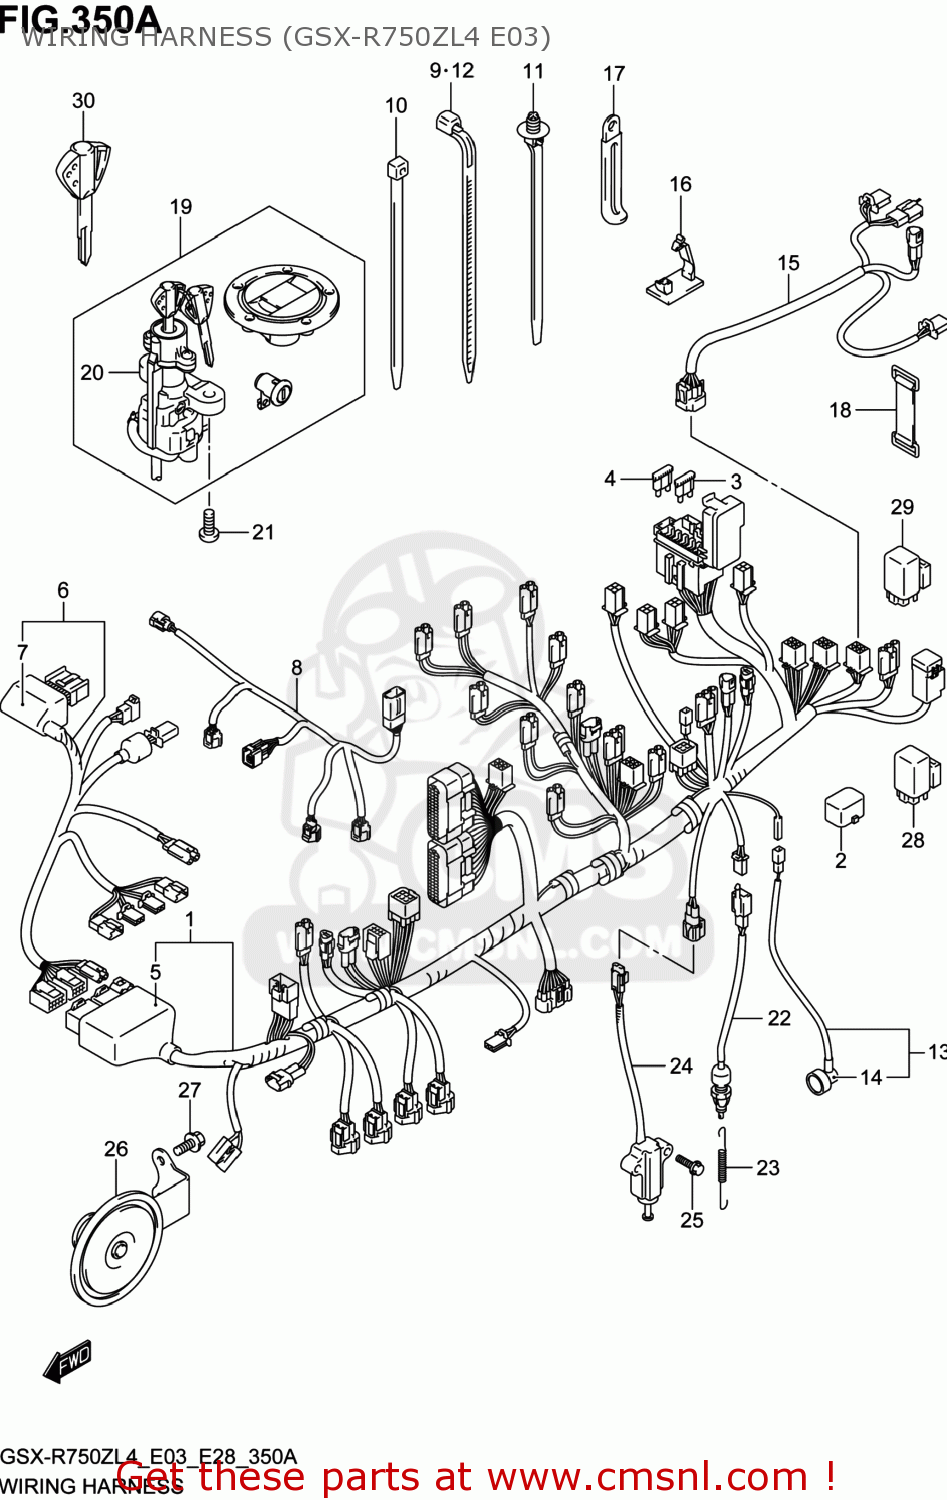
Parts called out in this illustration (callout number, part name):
1	HARNESS,WIRING NO.1
2	CAP,TS
3	FUSE(10A)
4	FUSE(15A)
5	COVER
6	HARNESS,WIRING NO.2
7	COVER,CONNECTOR
8	HARNESS,WIRING NO.3
9	CLAMP(L:95)
10	CLAMP(L:145)
11	CLAMP(L:154)
12	CLAMP(L:125)
13	WIRE,OIL PRESSURE SWITCH LEAD
14	CAP,OIL PRESSURE SWITCH
15	WIRE,RR COMB LEAD
16	CLAMP
17	CLAMP(L:45)
18	BAND
19	LOCK SET
20	LOCK ASSY,STEERING
21	BOLT(8X20)
22	SWITCH ASSY,STOP LAMP
23	SPRING
24	SWITCH ASSY,SIDE STAND
25	BOLT
26	HORN ASSY
27	BOLT
28	RELAY ASSY
29	RELAY ASSY
30	KEY,BLANK(IMMOBII)
